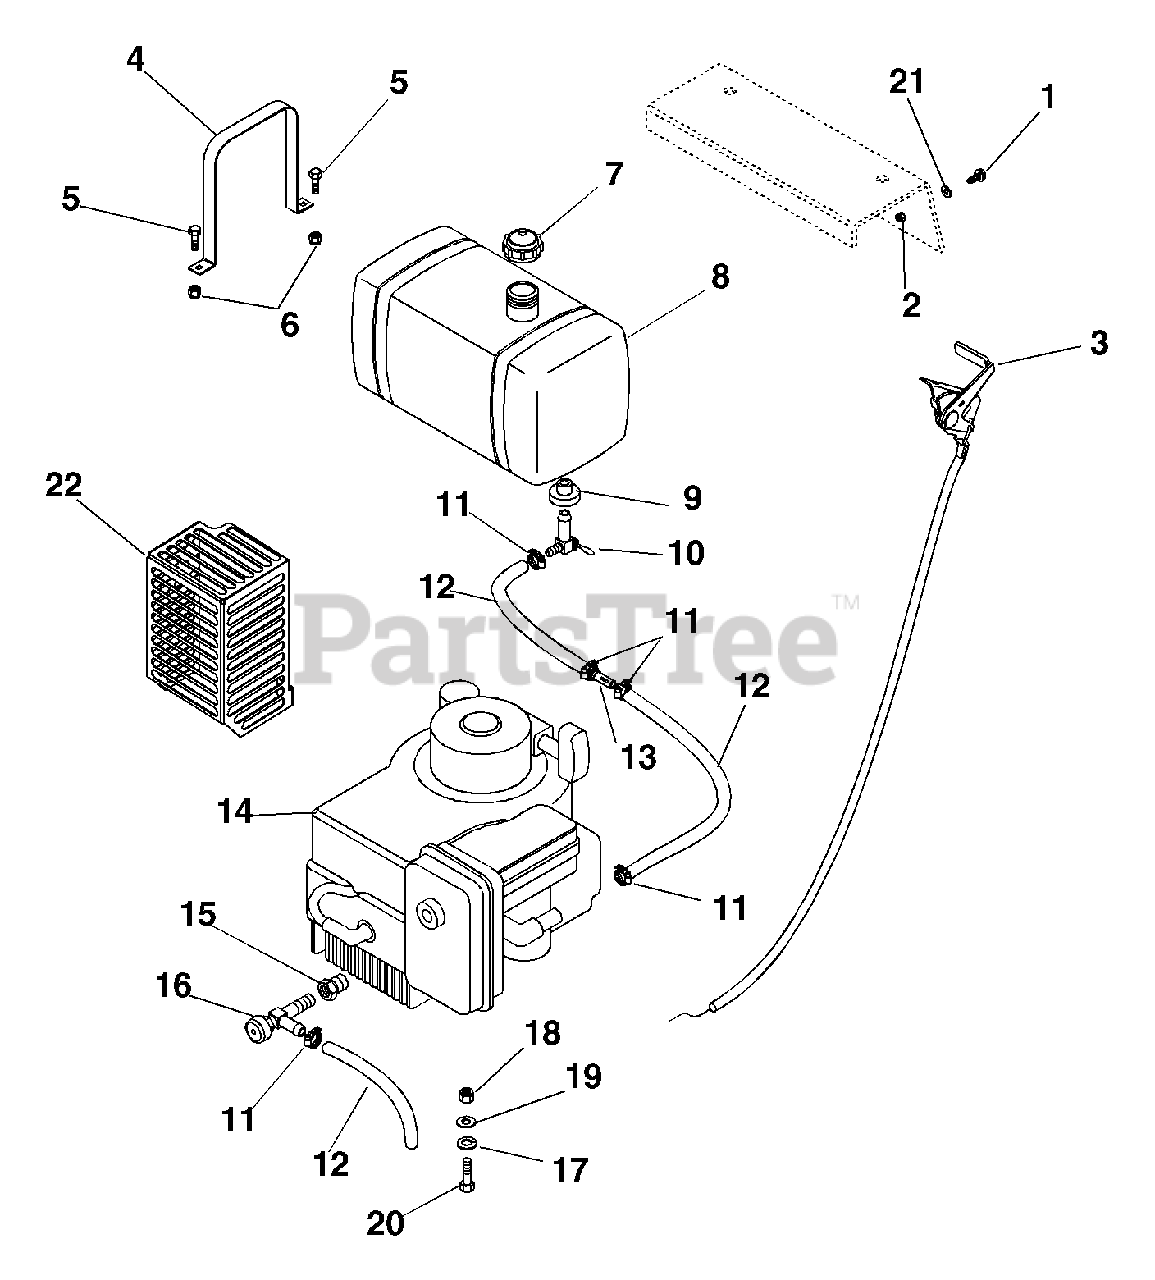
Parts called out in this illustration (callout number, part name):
1	Screw-Machine 10-24 x .50 Hex Washer Head
2	Nut-Locking-Nylon 10-24 with Insert
3	Cable, Control
4	Tank Strap For 4.5 Gallon Fuel Tank
5	Bolt-Hex .25-20 x .75 Grade 5
6	Nut-Locking-Center .25-20
7	Cap, Fuel Tank
8	Fuel Tank, 4.5 Gallon
9	Bushing Flange .375 x 1.06 x .625
10	Valve Ball Shut-Off
11	Clamp, Hose
12	Gas Line-Bulk .25" I.D.
13	Filter, Fuel
14	Engine, Kawasaki-12.5 H.P.
14	Engine, Kawasaki-14 HP OHV
15	Adapter, Oil Drain
16	Cock, Oil Drain
17	Washer-Locking .31 x .078 Regular
18	Nut-Locking-Center .31-18
19	Washer-Flat-Steel .344 x .688 x .065
20	Bolt-Hex M8 x 1.25 x 30 Grade 5
21	Washer-Flat-Steel .219 x .50 x .049
22	Weldment, Muffler Guard
